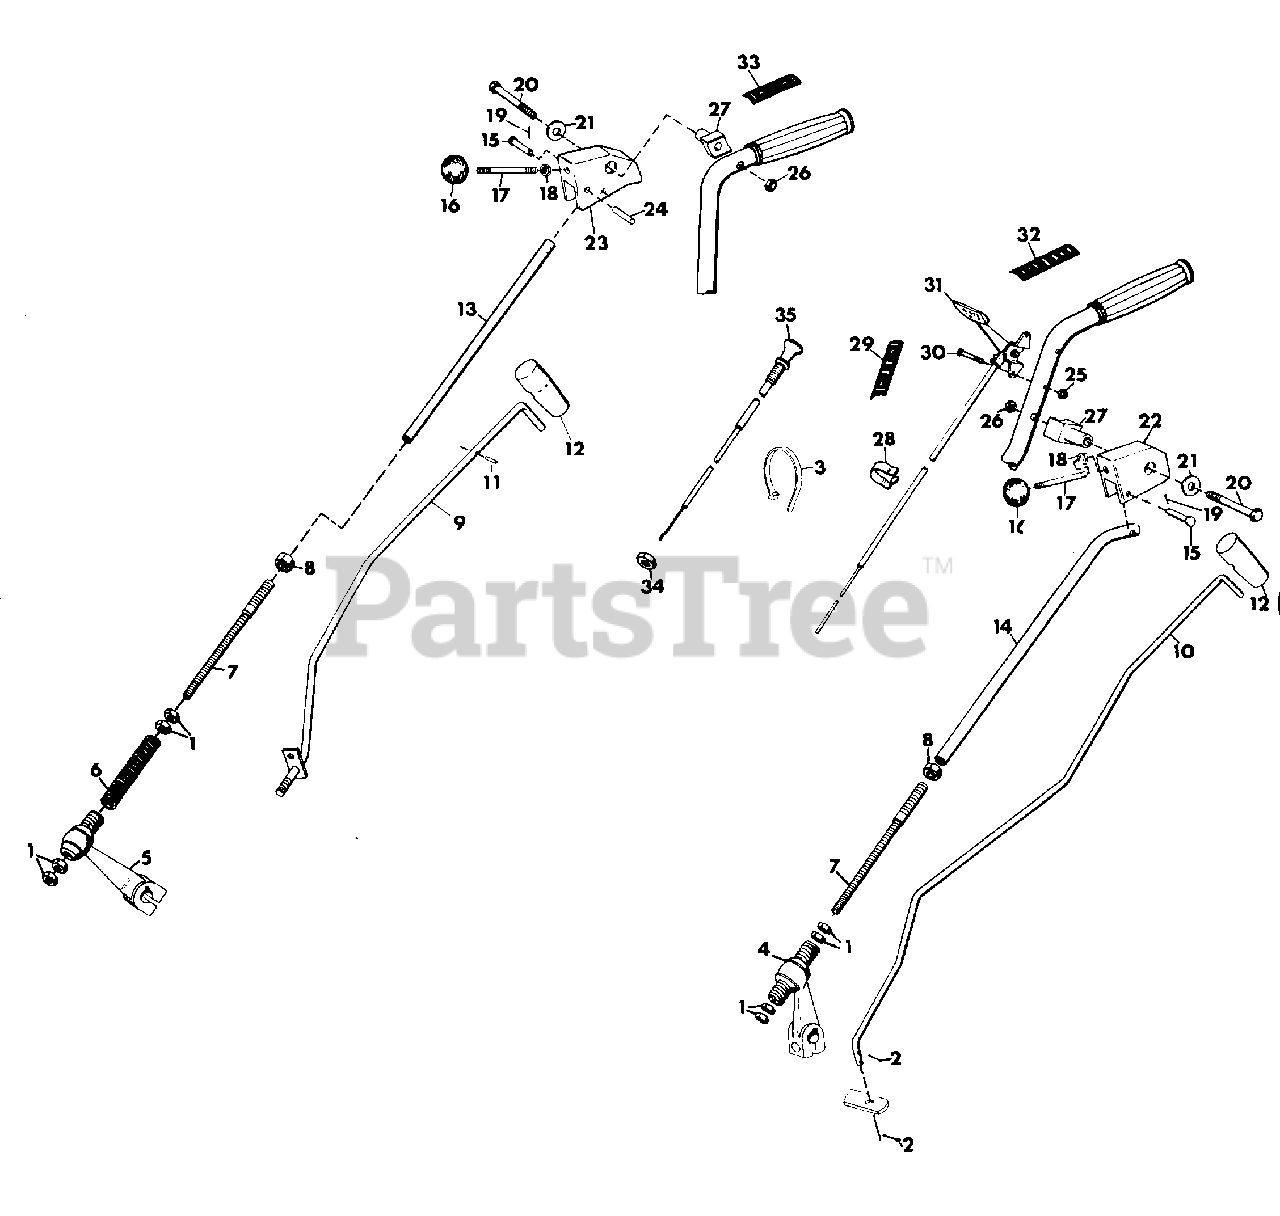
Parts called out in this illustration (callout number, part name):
1	JAM, HEX 3/8-16
2	PIN, COTTER .094X1.000
3	TIE, CABLE
4	ASSEMBLY, HI-LO LEVER
5	ASSEMBLY, FWD-REV LEVER
6	SPRING, FWD-REV NEUTRAL RETURN
7	ROD, CONTROL EXTENSION
8	NUT, JAM 1/2-13
9	ROD, 2-SPEED CONTROL(MODEL 5240,5260,5665,5645)
10	ROD, ATTACHMENT(MODEL 5240,5260,5665,5645)
11	PIN, SPRING .094X.688(MODEL 5240,5260,5665,5645)
12	HANDLE, RUBBER SHIFTER(MODEL 5200)
12	HANDLE, RUBBER SHIFTER(MODEL 5240,5260,5665,5645)
13	ROD, FWD-REV CONTROL
14	ROD, HI-LO CONTROL
15	PIN, CLEVIS .375X1.250
16	KNOB, CONTROL
17	ROD, SHIFTER
18	NUT, JAM 7/16-20 HEX
19	PIN, COTTER .125X.750
20	BOLT, HEX 1/2-13X3.50
21	WASHER, FLAT .531X1.062X.095
22	SUPPORT, HI-LO SHIFTER ROD
23	SUPPORT, FWD-REV SHIFTER ROD
24	PIN, SPRING .25X.125
25	NUT, LOCK 10-24
26	NUT
27	PIVOT, HANDLE LEVER
28	CLIP, CONDUIT
29	DECAL, GEAR SHIFT
30	SCREW, MACH 10-24X1.50 PAN HD
31	LEVER, THROTTLE CONTROL 8 H.P.
31	LEVER, THROTTLE CONTROL 12 H.P.
32	DECAL, THROTTLE
33	DECAL, FWD-REV
34	NUT, JAM 3/8-24 HEX(MODEL 5260,5665)
35	CONTROL, CHOKE(MODEL 5260,5665)
